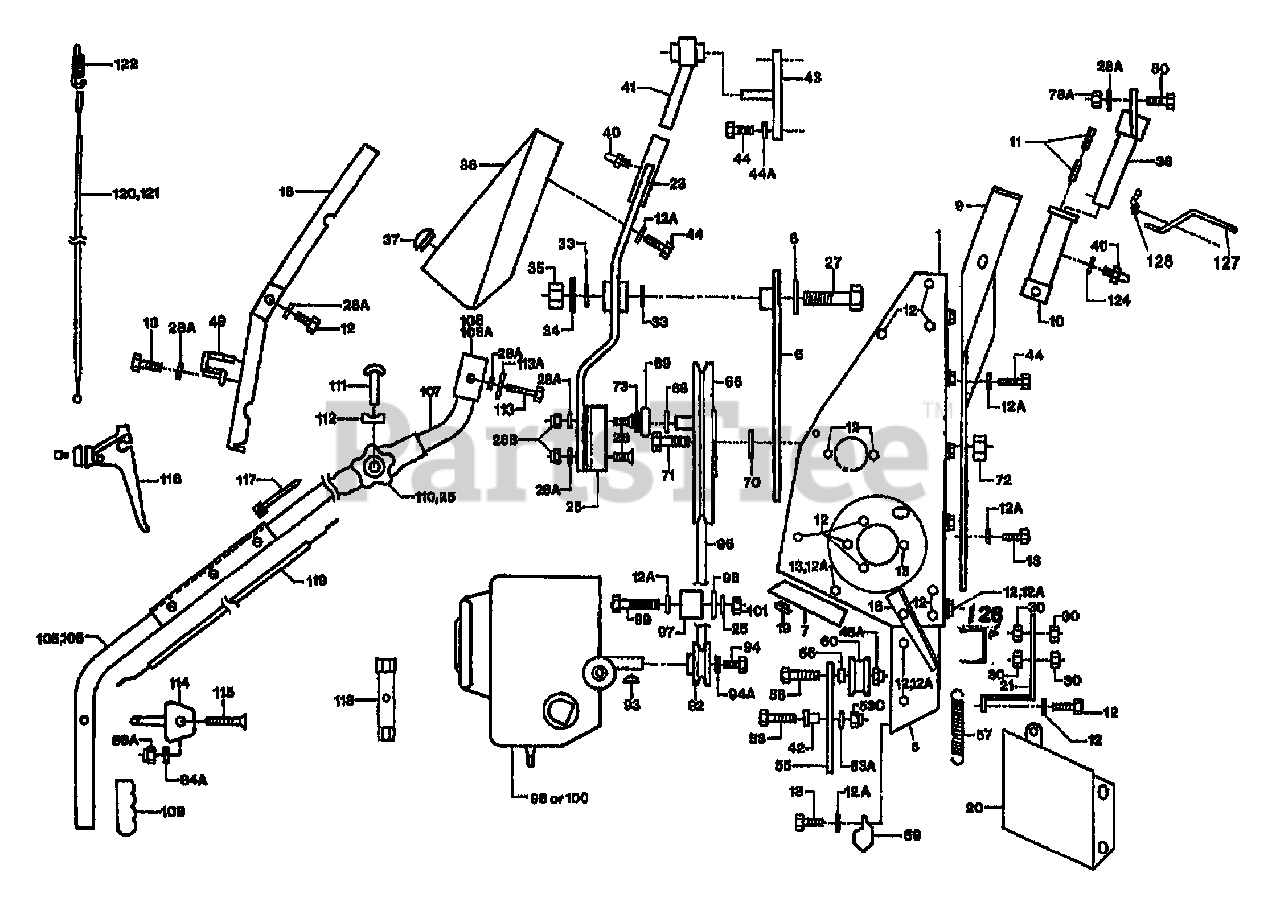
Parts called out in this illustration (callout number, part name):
1	THIS REF. NO. NOT USED
5	Plate-Engine Mount
6	Plate-Bottom Reinforcement
7	Frame Hood-Rear
8	Washer, Drive Arm, Bottom
9	Cutter Bar Weldment
10	Cutter Bar Holder
12	Screw-HHM8 x 12
12A	Washer
13	Screw-HHM8 x 16
16	Grass Shield-Wheel-RH
18	Hood w/Logo Decal
19	Plastic Plug
20	Cover-Drive Belt
21	Cover-Cutter Bar Belt
23	Drive Arm Assembly
25	Star Washer
26	Channel-Drive Arm
27	Drive Arm Pivot Bolt M16
28	Screw FHC 90° M8 x 30 Class 10.9
28A	Washer
28B	Nylon Nut M8 Class 10.9
33	Snap Ring
34	Washer, Drive Arm, Top
35	Nut-Nylon M16
36	Grass Shield w/Decal
37	Plastic Plug-Grass Shield
38	Mounting Shaft-Cutter Bar
39	Retaining Clip-M8 x 40
40	Grease Fitting-M6 x 100
41	Drive Socket and Bushing
42	Clutch Plate Blade Bushing
43	Mount-Cutter Bar
44	Screw-HHM8 x 20
44A	Washer
48A	Nylon Nut
49	Wheel Drive Cable Protector
50	Screw-M8 x 25
53	Screw-HHM10 x 35
53B	Nut-HM10
53C	Nut-Nylon-HM10
55	Clutch Plate Blade
56	Bushing-Idler
57	Spring-Blade Engagement
58	Screw-HHM12 x 45
59	Cutter Bar Cable Protector
66	Flywheel Blade w/Bng. Assy.
68	Spacer-Flywheel
69	Convex Bearing
70	Washer/Flywheel
71	Screw-M20-Flywheel
72	Nut-Flywheel
73	Circlip-Flywheel
78A	Nylon Nut
84A	Washer
86	Screw-HHM6 x 25
86A	Nylon Nut
92	Pulley-Cutter Bar
93	Key-Woodruff (Engine Pulley)
94	Screw-3/8-24 HH
95	V-Belt-Cutter Bar
99	Screw-HHM8 x 70
101	Nut-M8
105	Handlebar w/Decal & Grips
106	Upper Handlebars w/Decals & Grips
107	Lower Handlebars
108	Rubber Tube-Handlebar R/H
108A	Rubber Tube-Handlebar L/H
109	Grip-Handlebar
110	Knob-Handlebar
111	Bolt-Handlebar
112	Lock Clamp-Handlebar
113	Screw-HHM8 x 55
113A	Washer
114	Throttle Control w/Decal
115	Screw M6 x 45
116	Handlebar Lever-Control
117	Tie Strap
118	Wrench-Spark Plug
119	Throttle Cable
120	Cable-Cutter Bar
121	Cable-Wheel Drive
122	Washer-Wheel Drive
124	Washer
125	Grease Gun
126	Cutter Bar Belt Guide
127	Crank Pin
128	Clip for Crank Pin
